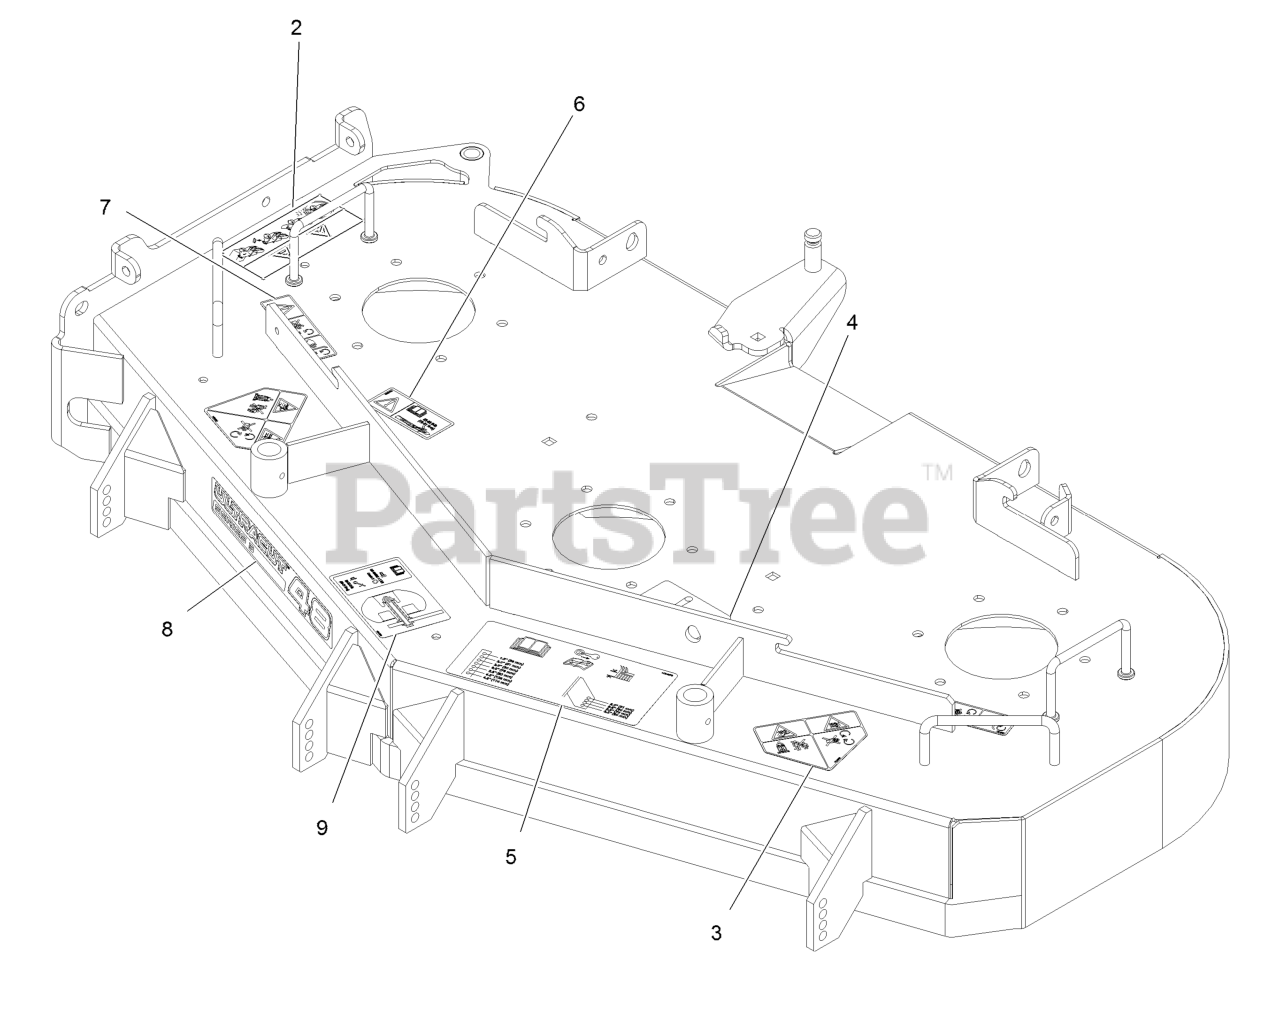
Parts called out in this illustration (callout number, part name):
2	Decal-Warning, Bagger
3	Decal-Danger
4	Decal-Belt Routing
5	Decal-Anti-Scalp
6	Decal-Bolt Torque
7	Decal-Cover, Missing
8	Decal-Ultracut 48 Series 3
9	Decal-Roller Mounting
